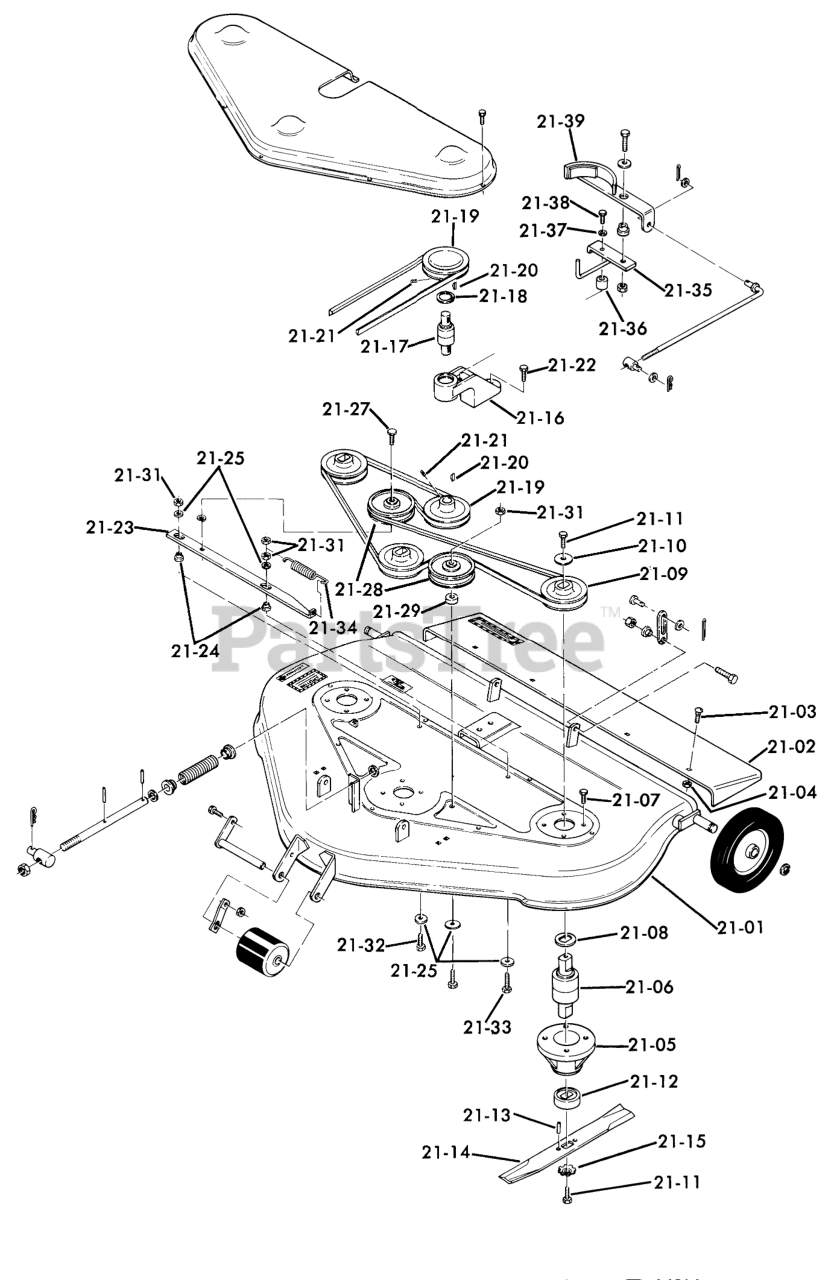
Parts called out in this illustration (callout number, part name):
21-01	Rear Discharge Mower Deck
21-01	Side Discharge Mower Deck
21-02	Extension-Chute
21-03	Bolt-Carriage
21-04	NUT
21-05	HOUSING-BEARING B
21-06	BEARING
21-07	Bolt
21-08	WASHER-DOUBLE D
21-09	PULLEY-MOWER DRIVE
21-10	WASHER
21-11	Bolt
21-12	Cup-Spindle
21-13	SPIROL ROLL PIN
21-14	BLADE KIT
21-15	WASHER
21-16	HOUSING DRIVE BRG R
21-17	BEARING INTEG SHAFT
21-18	Snap Ring
21-19	Pulley
21-20	KEY-WOODRUFF
21-21	Set Screw
21-22	Bolt
21-23	BAR-IDLER SUPPORT
21-24	SPACER
21-25	WASHER
21-27	BOLT HEX SPECIAL
21-28	Idler Pulley
21-29	Spacer
21-31	Nut
21-32	Bolt
21-33	Bolt
21-34	SPRING-EXTENSION
21-35	Pivot Bracket
21-36	Spacer
21-37	LOCKWASHER
21-38	BOLT
21-39	Support and Brake Lining
